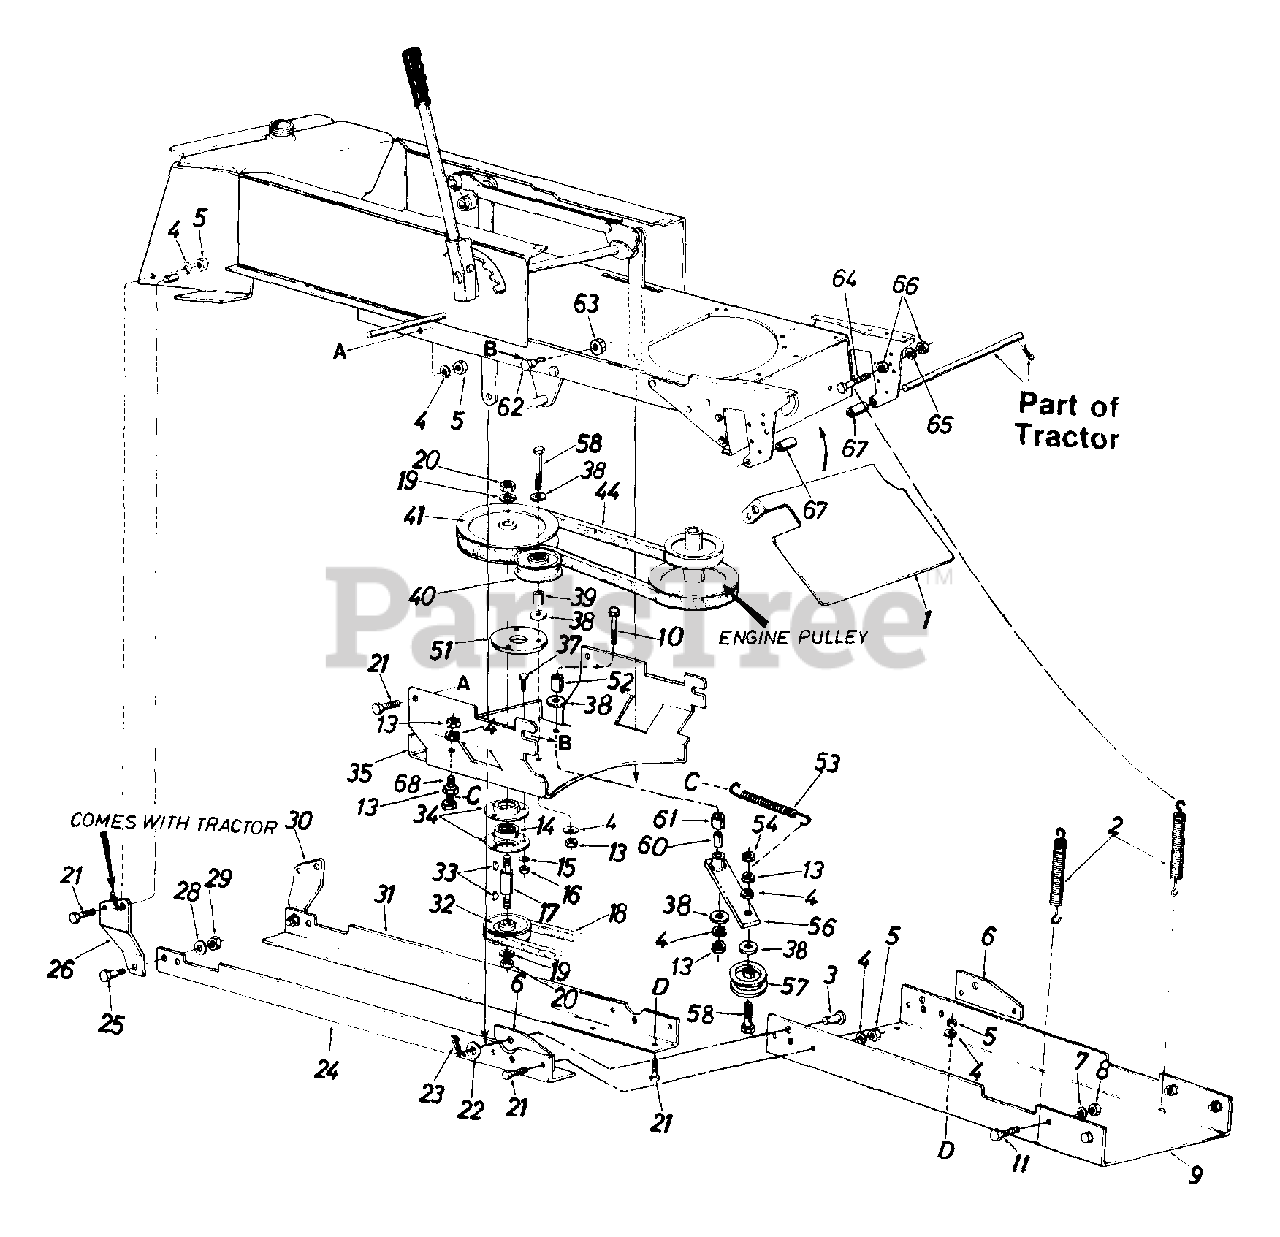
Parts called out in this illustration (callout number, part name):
3	Clevis Pin
4	L-Wash. 3/8" I.D.
5	Hex L-Nut 3/8-24 Thd.
6	Attaching Plate
7	L-Wash. 1/2" I.D.
8	Hex L-Nut 1/2-20 Thd.
11	Hex Bolt 1/2-20 x 1.25" Lg.
13	Hex Jam Nut 3/8-16 Thd.
14	Ball Bearing
15	L-Wash. 5/16" I.D.
16	Hex Nut 5/16-18 Thd.
17	Spindle
18	V-Belt
19	L-Wash. 5/8" I.D.
20	Hex Jam Nut 5/8-11 Thd.
21	Hex Bolt 3/8-24 x 1.00" Lg.
22	Flat Washer
23	Internal Cotter Pin
26	Rear Hanger Brkt.
28	L-Wash. 7/16" I.D.
29	Hex Nut 7/16-14 Thd.
30	Rear Hanger Brkt. - L.H.
31	Rear Support Angle - L.H.
32	Lower Drive Pulley 5/8 x 5.56
33	#6 Hi-Pro Key 3/16 x 5/8" Dia.
34	Bearing Housing
35	Supporting Bracket
37	Hex Sems Bolt 5/16-18 x 1"
38	Fl-Wash. .38" I.D. x 1" O.D.
39	Spacer .38" I.D. x .62" O.D.
40	Fl-Idler Pulley
41	Upper Drive Pulley
44	V-Belt
53	Extension Spring 4.75" Lg.
54	Hex L-Nut 3/8-16 Thd.
56	Idle Arm Ass'y.
57	Idler Pulley
58	Hex Bolt 3/8-16 x 2.25" Lg.
60	Spacer .377" I.D. x .83" Lg.
61	Spacer .38" I.D. x .565" Lg.
62	Shoulder Bolt .498" Dia.
63	Hex L-Nut 3/8-16 Thd.
64	Hex Bolt 1/4-28 x 1.50" Lg.
65	L-Wash. 1/4" I.D.
66	Hex Nut 1/4-28 Thd.
67	Spacer .63" I.D. x 1.75" Lg.
68	Hex Bolt 3/8-16 x 2" Lg.
